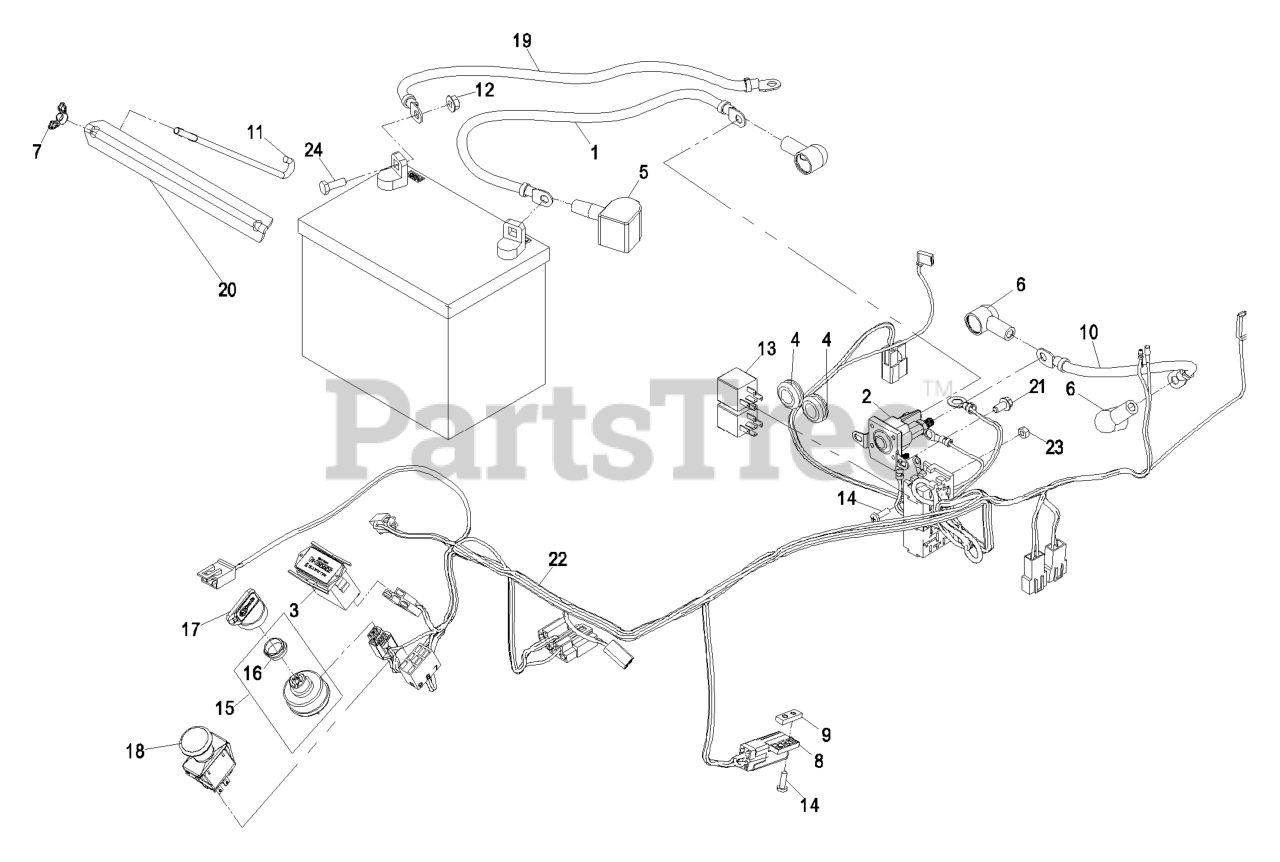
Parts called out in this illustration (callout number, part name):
3	METER-HOUR
4	GROMMET
6	INSULATOR-SOLENOID
7	WINGNUT
9	PLATE-TAPPED
11	BOLT-HOLDDOWN
14	SCREW-PPH
15	ASM,SWITCH W/NUT
16	NUT-SWITCH, IGNITION
17	KEY-IGNITION
18	SWITCH-PTO
19	CABLE-BATTERY, NEGATIVE
20	ANGLE-BATTERY
21	SCREW-HWH
22	HARNESS-WIRE
23	NUT-LOCK, NI
24	SCREW-HH
